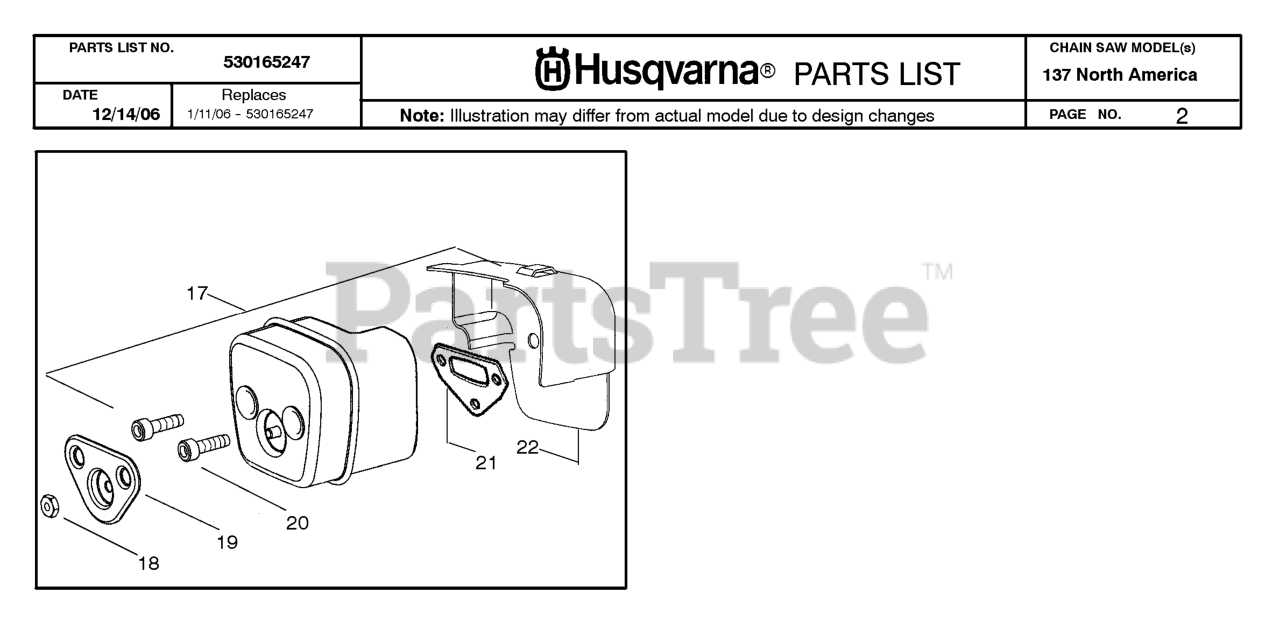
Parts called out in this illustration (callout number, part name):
17	MUFFLER KIT
18	NUT-BRASS
19	COVER BOLT
20	SCREW MUFFLER
21	GASKET-MUFFLER
22	BACKPLATE, MUFFLER
